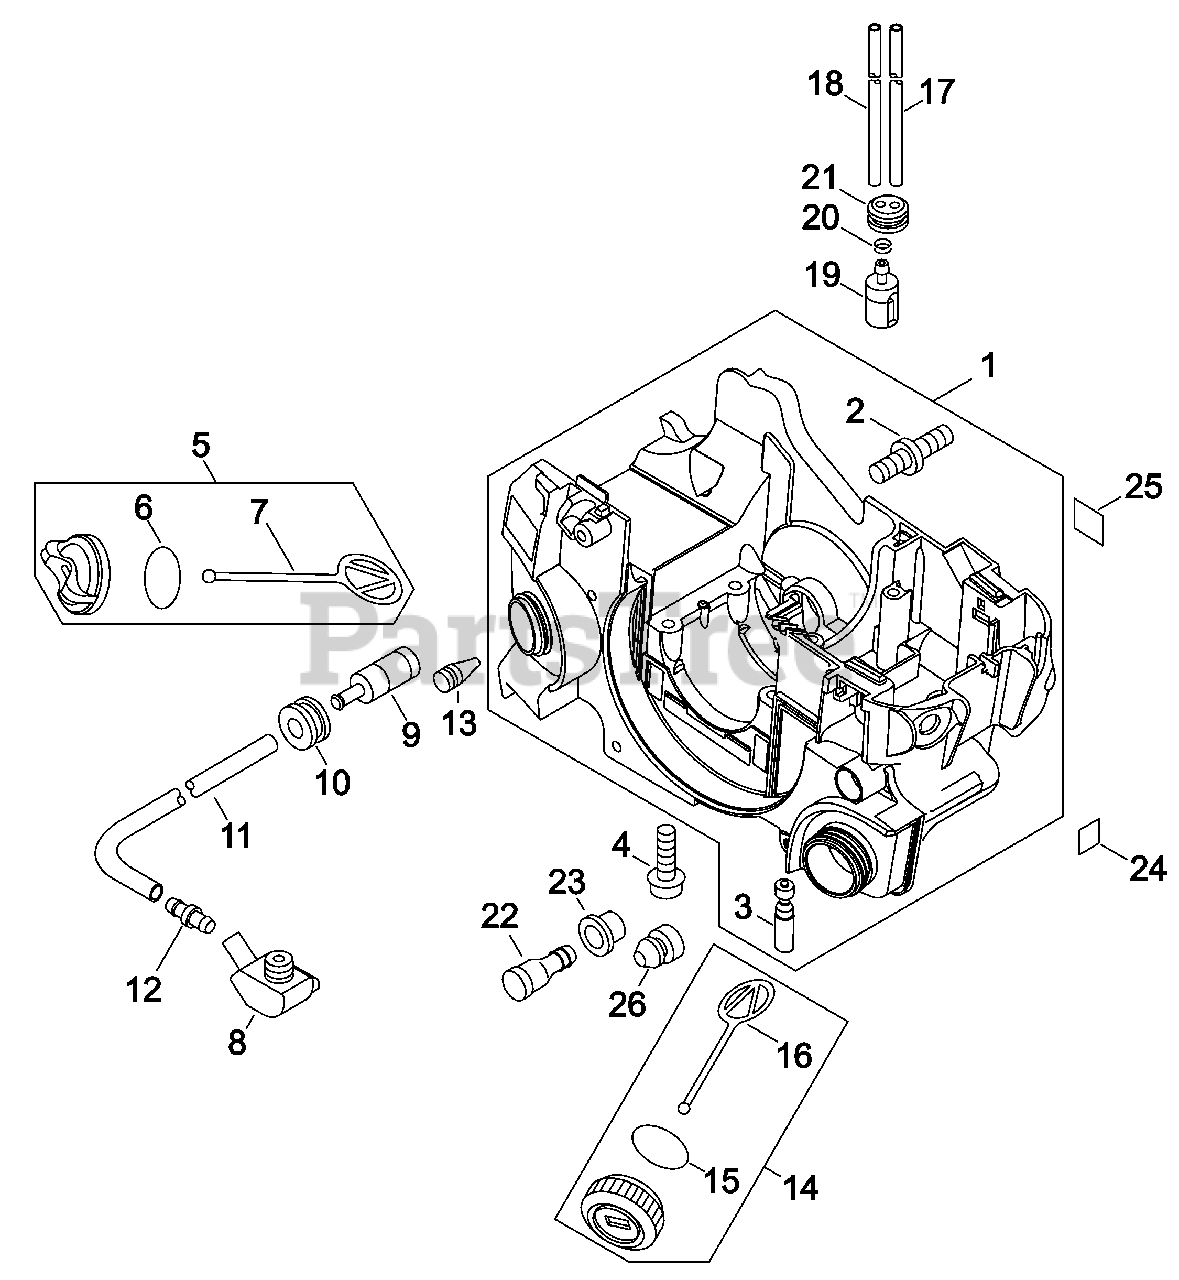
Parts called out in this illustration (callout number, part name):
1	COVER ASSY, ENGINE
2	BOLT, STUD 8
3	AUTO-OILER ASSY
4	BOLT, TORX 5×30
5	CAP ASSY, OIL
6	O-RING 18
7	CONNECTOR, CAP L= 60mm
8	GROMMET, OIL
9	FILTER, OIL
10	GROMMET
11	PIPE 3×6×185mm BLACK
12	CONNECTOR, PIPE
13	VENT ASSY
14	CAP ASSY, FUEL
15	O-RING 22
16	CONNECTOR, CAP L= 60mm
17	PIPE, FUEL RETURN 2.4×5×80 BLACK
18	PIPE, FUEL 3×5×230 BLACK
19	FILTER, FUEL
20	CLIP Ø6
21	GROMMET, FUEL
22	VENT ASSY
23	GROMMET, FUEL
24	LABEL, ON-OFF
26	CUSHION
